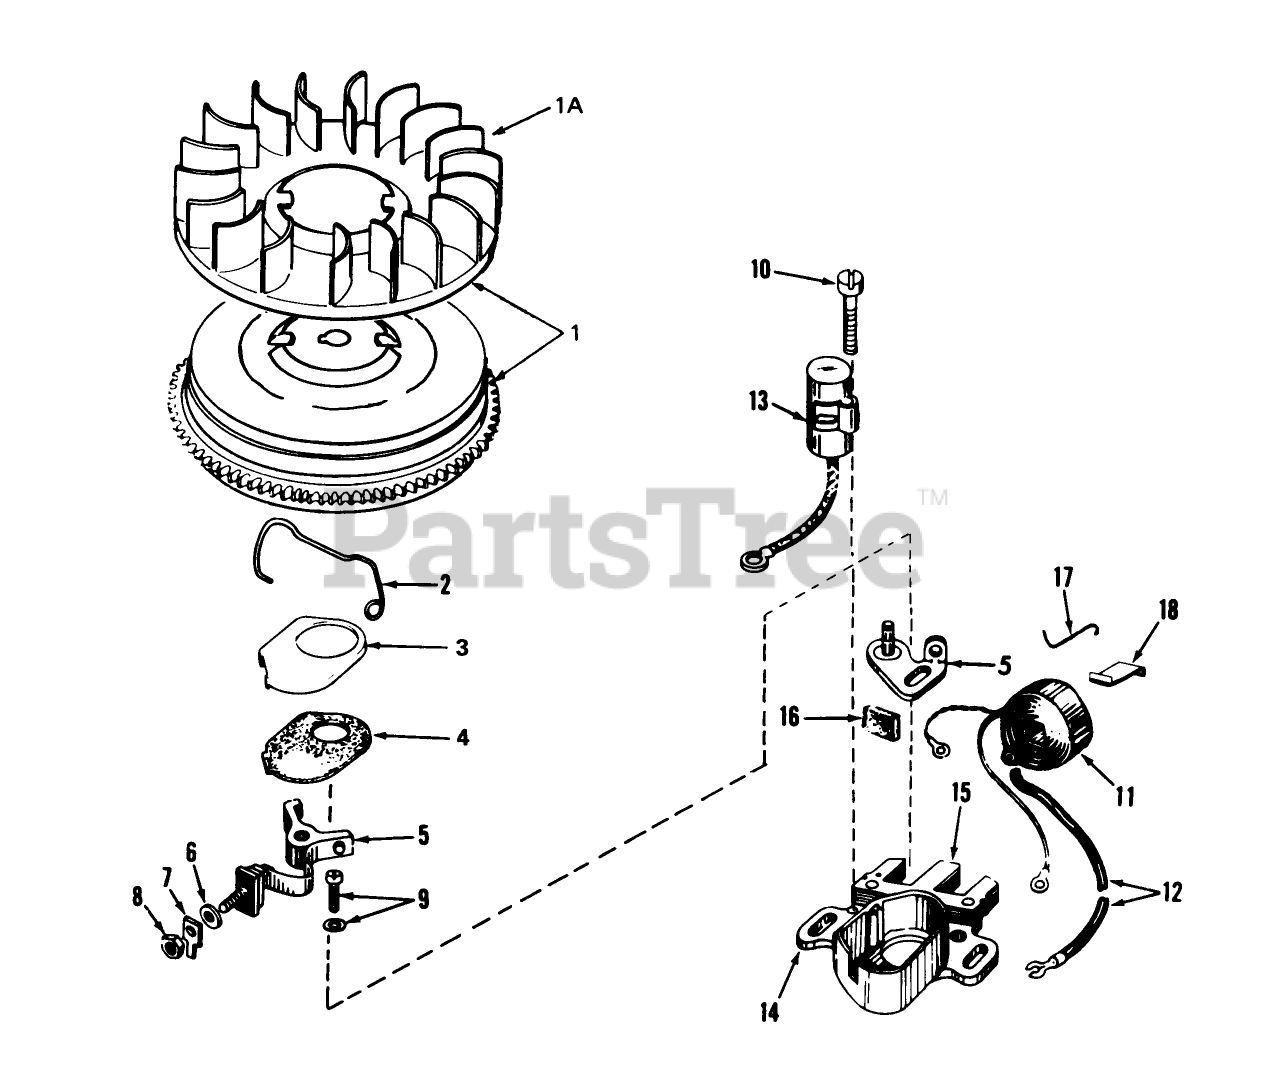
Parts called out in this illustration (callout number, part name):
1	Flywheel (Incl. Ref. #1A)
1A	Fan
2	Spring Breaker Box
3	Cover-Dust
4	Gasket, Dust Cover
5	Breaker Assy.
6	Washer
7	Terminal, Ground
8	DECAL
9	Breaker Screw
10	Condenser Screw
11	Coil Assembly (Incl. Ref. #12)
12	Wire, Lead
13	Condenser
14	Core & Plate
15	Stator Assembly (Incl. Ref. #2 thru 14, 16, 17 & 18)
16	Felt,Cam Wiper
17	Clip, Coil
18	Spring Coil Wedge
